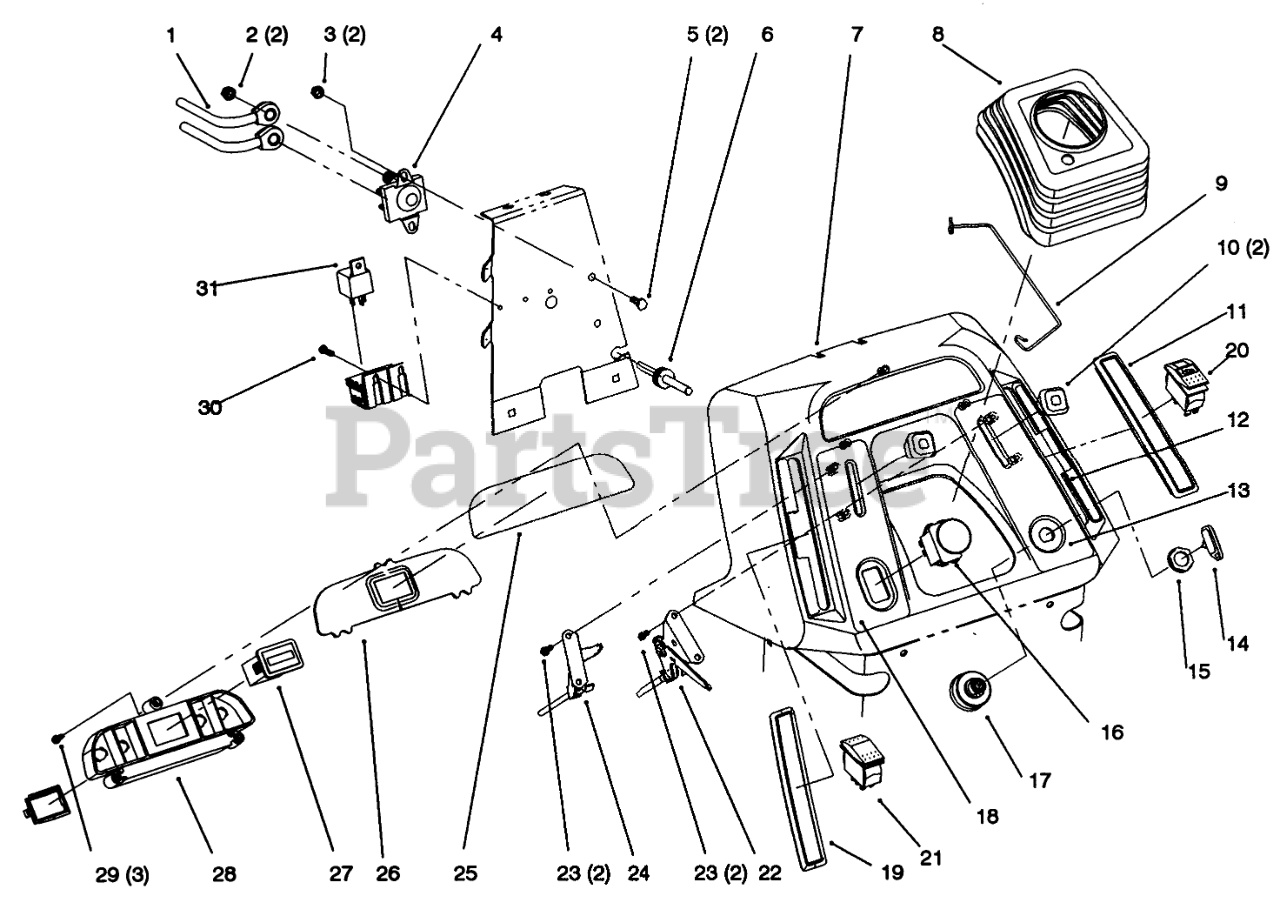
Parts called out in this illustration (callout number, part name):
8	BOOT-STEERING
9	CLIP-BOOT
11	COVER-SLOT, RH
13	DECAL-THROTTLE, IGNITION
14	KEY-IGNITION
16	SWITCH-PTO
17	SWITCH-IGNITION
18	DECAL-PTO / CHOKE
19	COVER-LIFT
20	SWITCH-CRUISE
21	SWITCH
22	CONTROL-THROTTLE (TWIN)
24	CONTROL-CHOKE (TWIN)
25	DECAL - DASH LENS
26	LENS-DASH
27	HOURMETER
28	6 LIGHT HOUSING
29	SCREW-PPH
30	SCREW-PPHTF
31	RELAY
